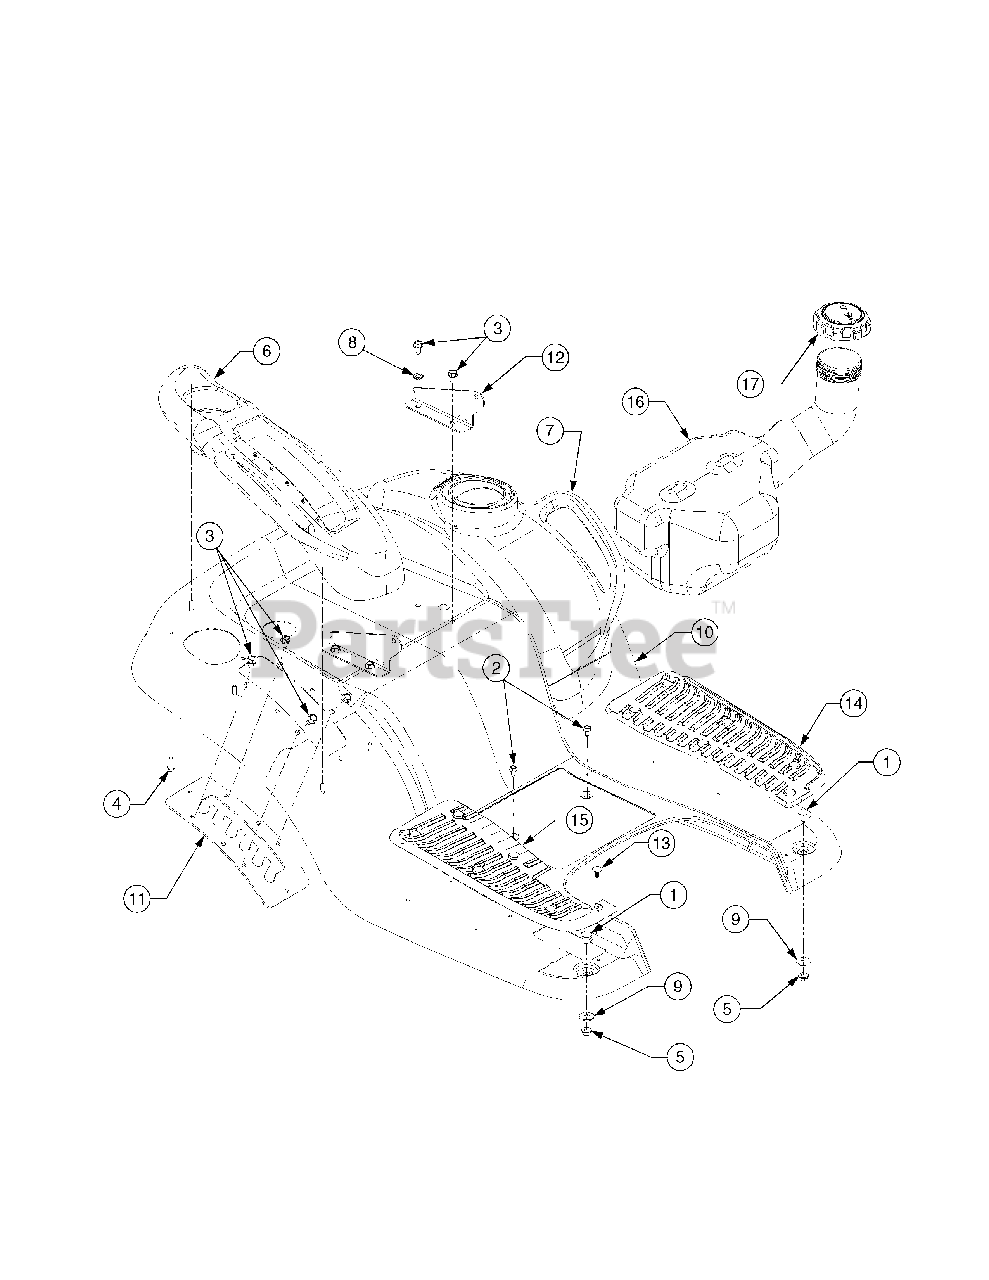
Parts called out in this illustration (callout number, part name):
1	Bolt, Carriage, 5/16-18 x .75 Lg
2	Screw, Hex Wash Hd Tap, 1/4-20 x .5
3	Screw, Hex Wash Hd Tap, 5/16-12, 0.75
4	Screw, 1/4-15, 0.750
5	Nut, Flange Insert Lock, 5/16-18 GRF
6	Cover, Fender, RH
7	Cover, Fender, LH
8	Washer, External Tooth Lock, 5/16
9	Washer, Flat, .349 x 1.00 x .063
13	Clip, Ratchet, .250 Dia
14	Pad, Foot, LH
15	Pad, Foot, RH
16	Tank, Fuel
17	Cap, Fuel
